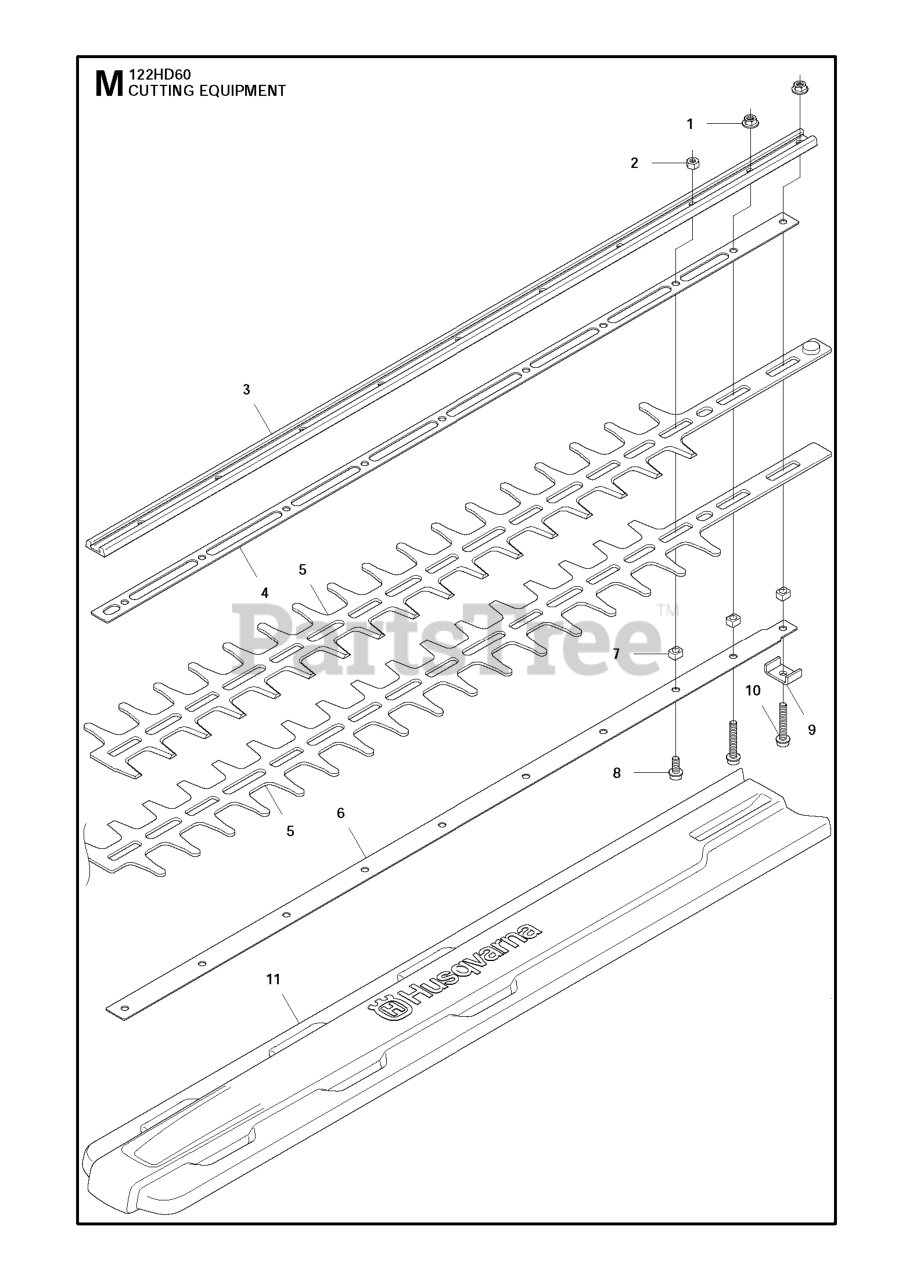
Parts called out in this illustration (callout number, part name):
4	WEAR PLATE
5	BLADE HEDGE TRIMMER
8	SCREW
11	TRANSPORT GUARD
